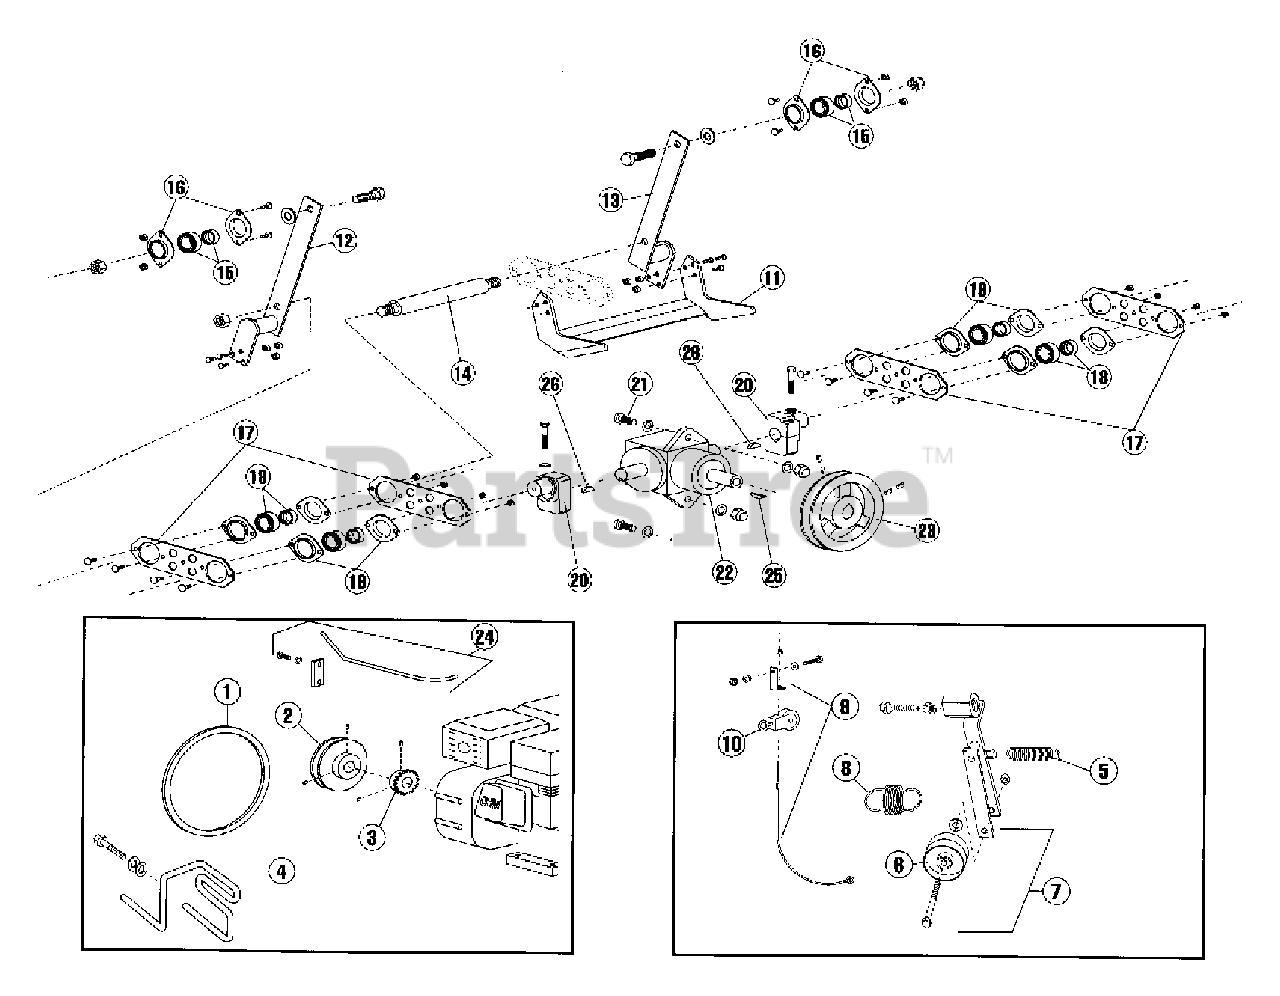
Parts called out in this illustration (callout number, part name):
1	V-belt, A-26" special
2	V-pulley 4" special, with key
3	Sprocket with key, engine
4	Belt keeper kit with hardware
5	Spring , 3 3/4"
6	Pulley, idler 2 3/4"
7	Belt idler assembly
8	Spring, 4", blade/clutch
9	Cable, blade/clutch with hardware
10	Pulley, swivel eye, clutch
11	Blade with hardware
12	Blade arms and shaft
13	Bearing, 3/4" with locking collar with fasteners
14	Stamping kit,
15	Plate, rod
16	Bearing, 1" with locking collar
17	Stamping kit, with fasteners (1" bearing)
18	Crank, eccentric kit
19	Hardware kit, gear box
20	Gear box, right angle "T" drive
21	Pulley 5 1/4" OD, with key, gear box
22	Tube, throttle cable, assembly
23	Key, #6 woodruff (5/32 x 5/8)
24	Key, #9 woodruff (3/16 x 3/4)
